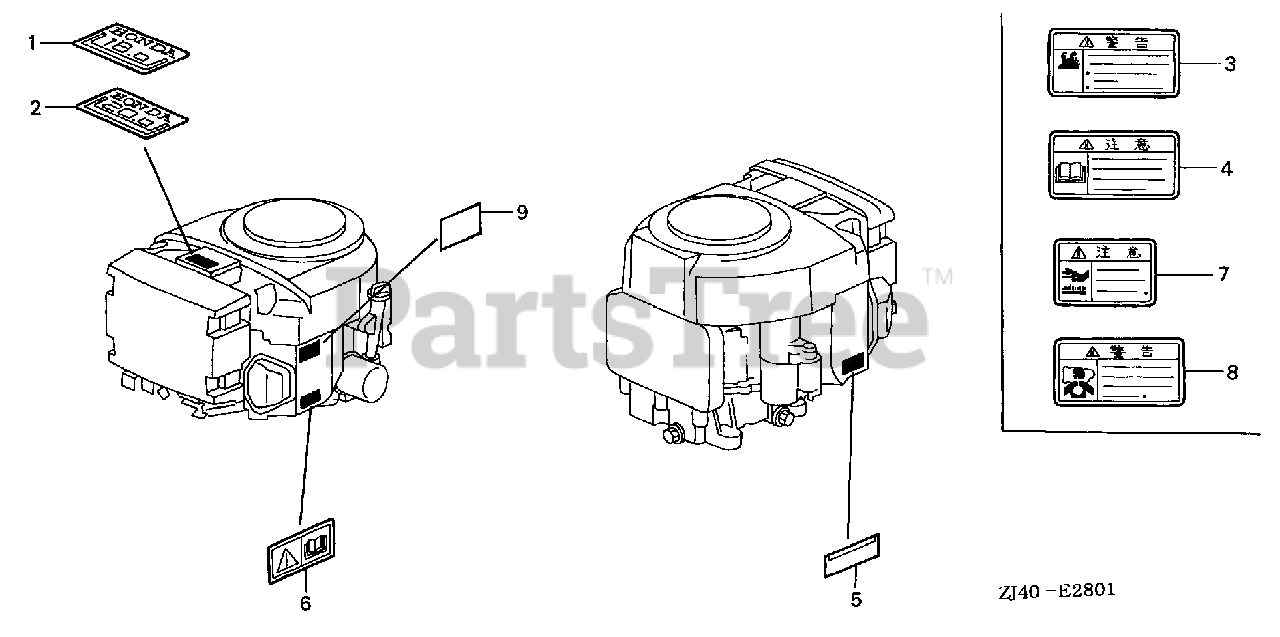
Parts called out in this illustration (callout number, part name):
2	MARK, EMBLEM
2	EMBLEM
3	MARK, FUEL WARNING
4	MARK, CAUTION (J)
5	LABEL, SPECIFICATION (GXV620)
6	MARK, OPERATOR CAUTION
7	MARK, HEAT CAUTION
8	MARK, EX. GAS WARNING
9	LABEL (E-SPEC)
